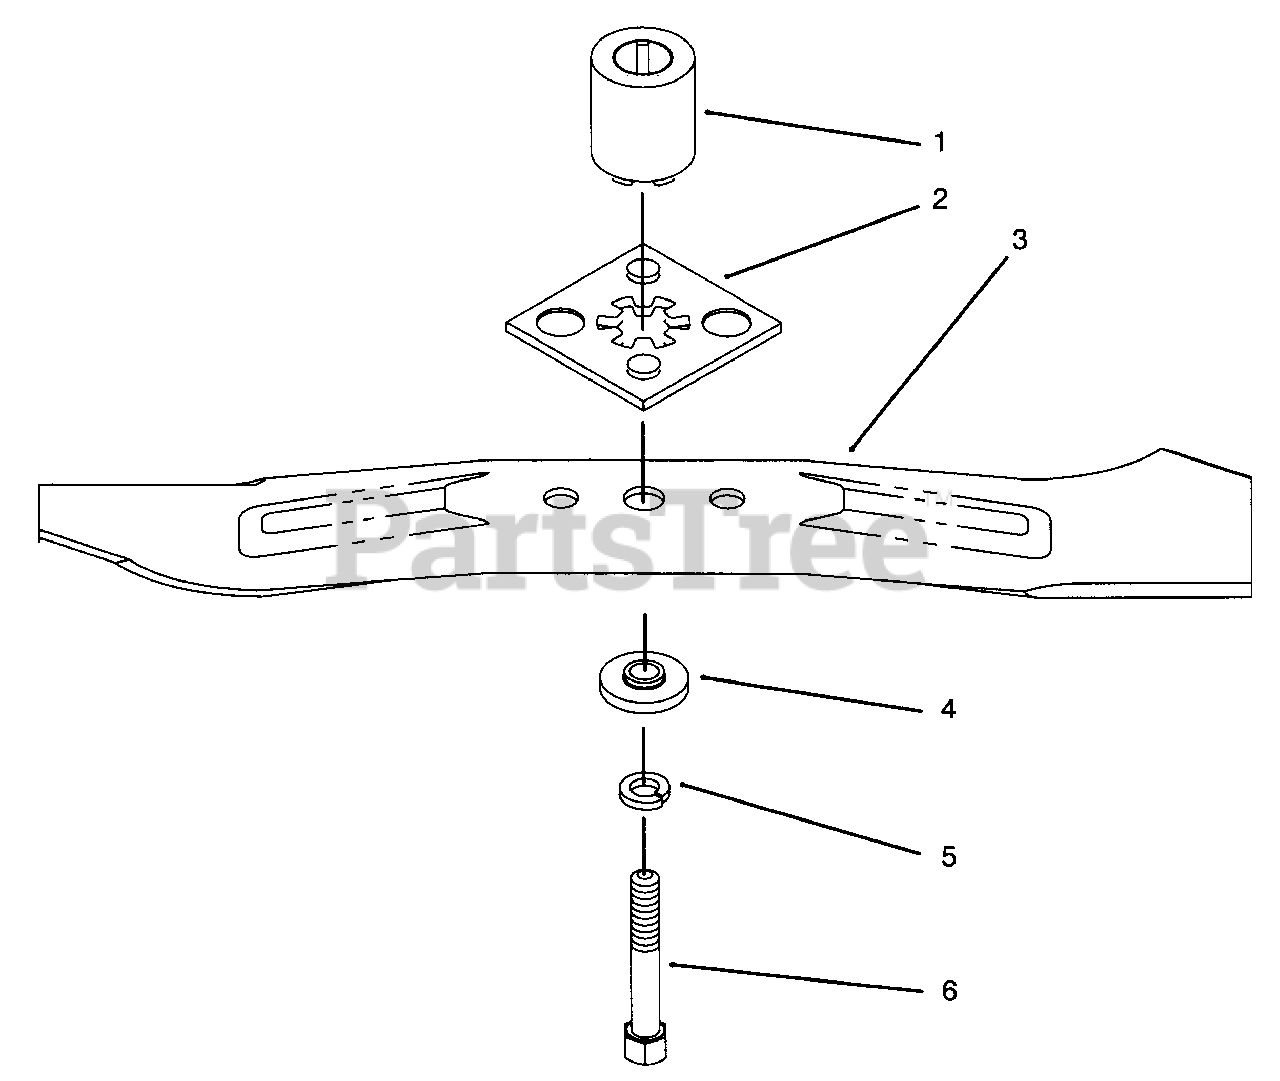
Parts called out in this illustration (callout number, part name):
1	Hub-Blade Driver
2	Plate-Blade Driver
3	Blade-48cm
4	Spacer-Blade
5	Washer-Lock
6	Bolt-Blade
